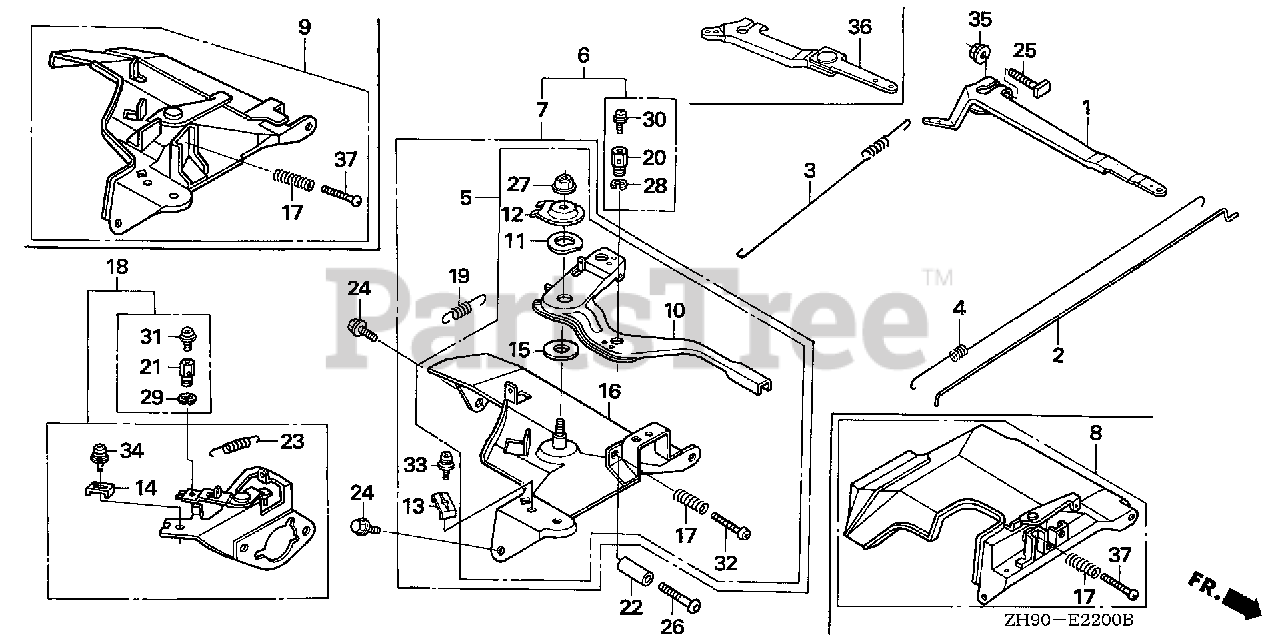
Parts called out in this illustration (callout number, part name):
1	ARM, GOVERNOR
2	ROD, GOVERNOR
3	SPRING, GOVERNOR (L=145.0MM) (WIRE DIAMETER 1.0MM)
4	SPRING, THROTTLE RETURN
7	CONTROL ASSY. (REMOTE)
10	LEVER, CONTROL
11	SPRING, LEVER
12	WASHER, CONTROL LEVER
13	HOLDER, CABLE
15	SPACER, CONTROL LEVER
16	BASE, CONTROL
17	SPRING, CONTROL ADJUSTING
19	SPRING, CABLE RETURN
24	BOLT, FLANGE (6X12) (CT200)
25	BOLT, GOVERNOR ARM
27	NUT, SELF-LOCK (6MM)
32	SCREW, PAN (5X28)
33	SCREW, PAN (5X16)
33	SCREW-WASHER (5X16)
35	NUT, FLANGE (6MM)
